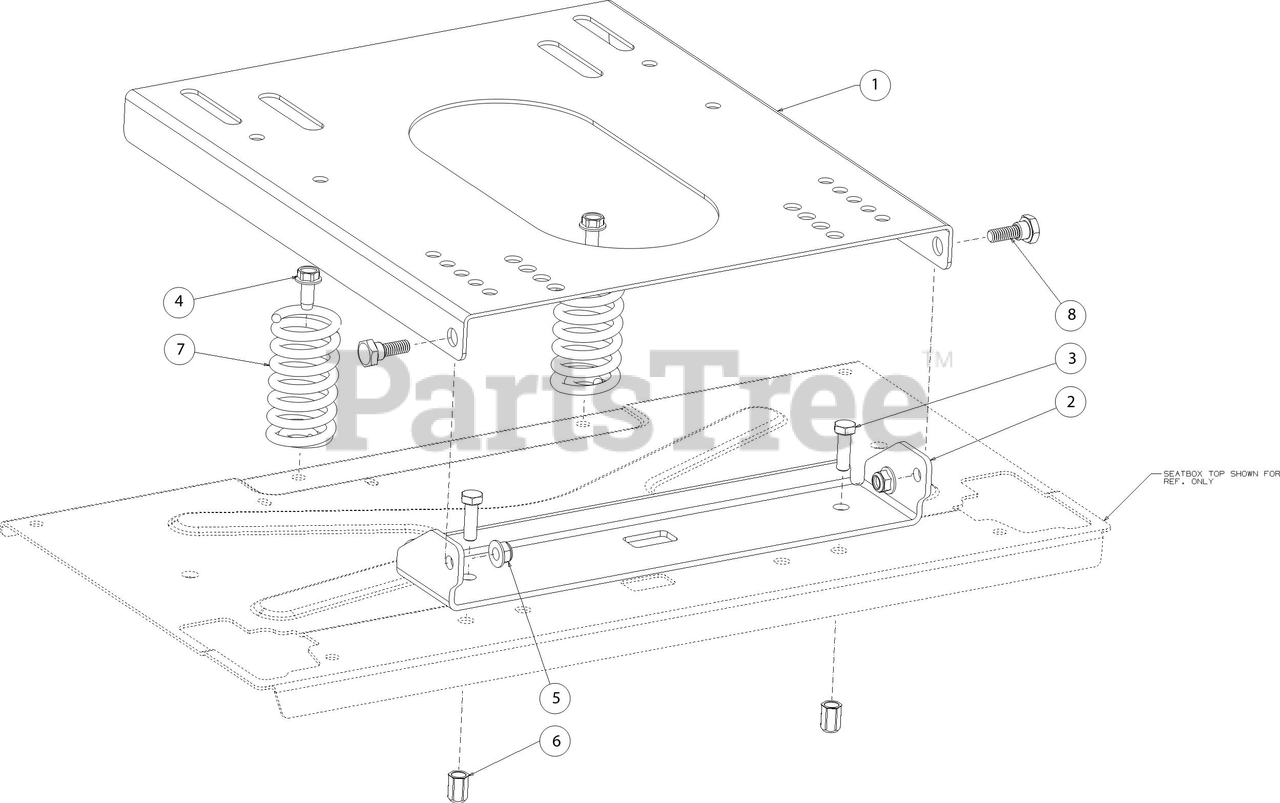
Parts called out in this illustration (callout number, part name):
1	SEAT PLATE DUAL KNOB BASE
2	SEAT PIVOT BRACKET
3	SCREW 5/16-18 X 1.00 GR5
4	SCREW 5/16-18 X .750
5	FLANGE LOCK NUT 5/16-18
6	NUT RIVET 5/16-18
7	COMPRESSION SPRING
8	SHOULDER SCREW .437
